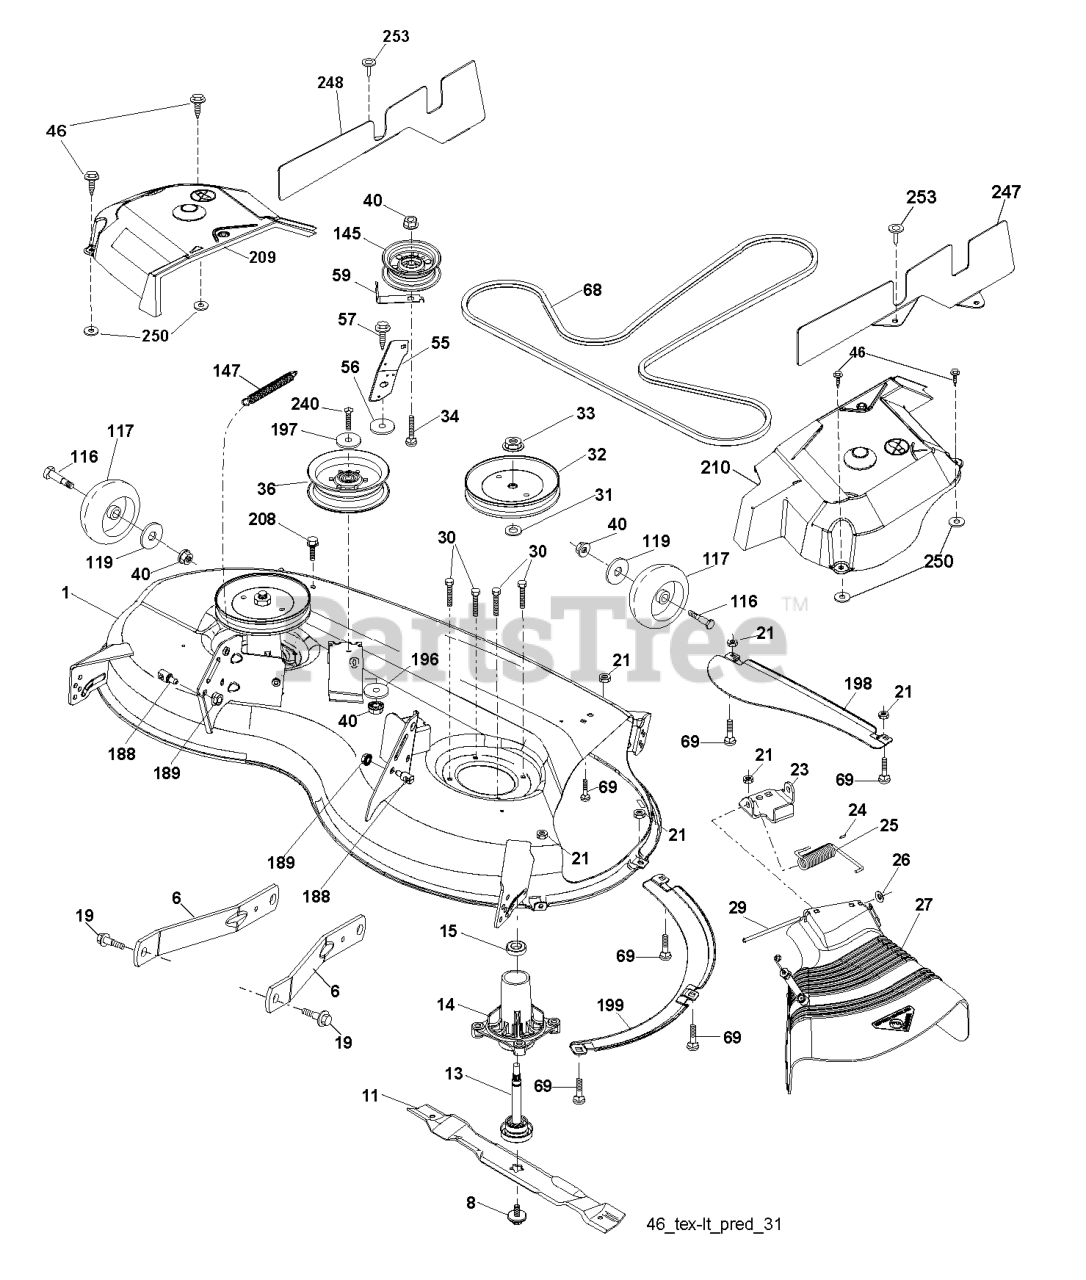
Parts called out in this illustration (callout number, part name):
1	DECK.WELDMENT.46"
6	ARM.SUSPENSION.MOWER.R
8	BOLT.WASHER.ASM.7/16-2
11	BLADE.MOWER.46".HI.LIFT
13	SHAFT.ASM.MDRL.N/GREASE.38
14	RP.HOUSING.MANDREL.4PT.
19	BOLT.SHOULDER
21	LOCKNUT
23	BRKT.DEFLECTOR.38"2005+
24	CAP-SLEEVE LT
25	SPRING.TORSION.DEFLECT
26	NUT PUSH M
29	ROD.HINGE
30	SCREW, WASHER HEAD
31	WASHER.SPACER.MANDREL
32	PULLEY.MANDREL.5.438.PD
33	NUT.FLANGE.LOCK.TOP
34	BOLT.3/8-16X1.50
36	PULLEY.IDLER.2006
40	NUT LOCK FLG 3/8-16 UNC
46	SCREW.1/4-20X5/8
56	SPACER.RETAINER
57	SCREW 3/8-16X1
59	GUARD, BELT
68	V-BELT
69	BOLT
116	BOLT.SHOULDER.3/8-16X3-5/8.
117	RP WHEEL. GUAGE RALLY
118	NUT LOCK FLG 3/8-16 UNC
119	WASHER
145	PULLEY.IDLER.48"PRIMARY
147	SPRING.MOWER.DRIVE.ELECTRIC
188	STUD.FASTNER.W/ANTI-ROTATE
189	NUT LOCK HEX FLANGE 5/16-18
197	WASHER
198	BAFFLE CENTER FRONT
199	BAFFLE FRONT RH
200	WASHER.13/32 X 1 X 1/2.11GUARD
208	SCREW 3/8-16X1/2
240	BOLT-HEX EAK
250	PALNUT 1/4
253	SCREW
